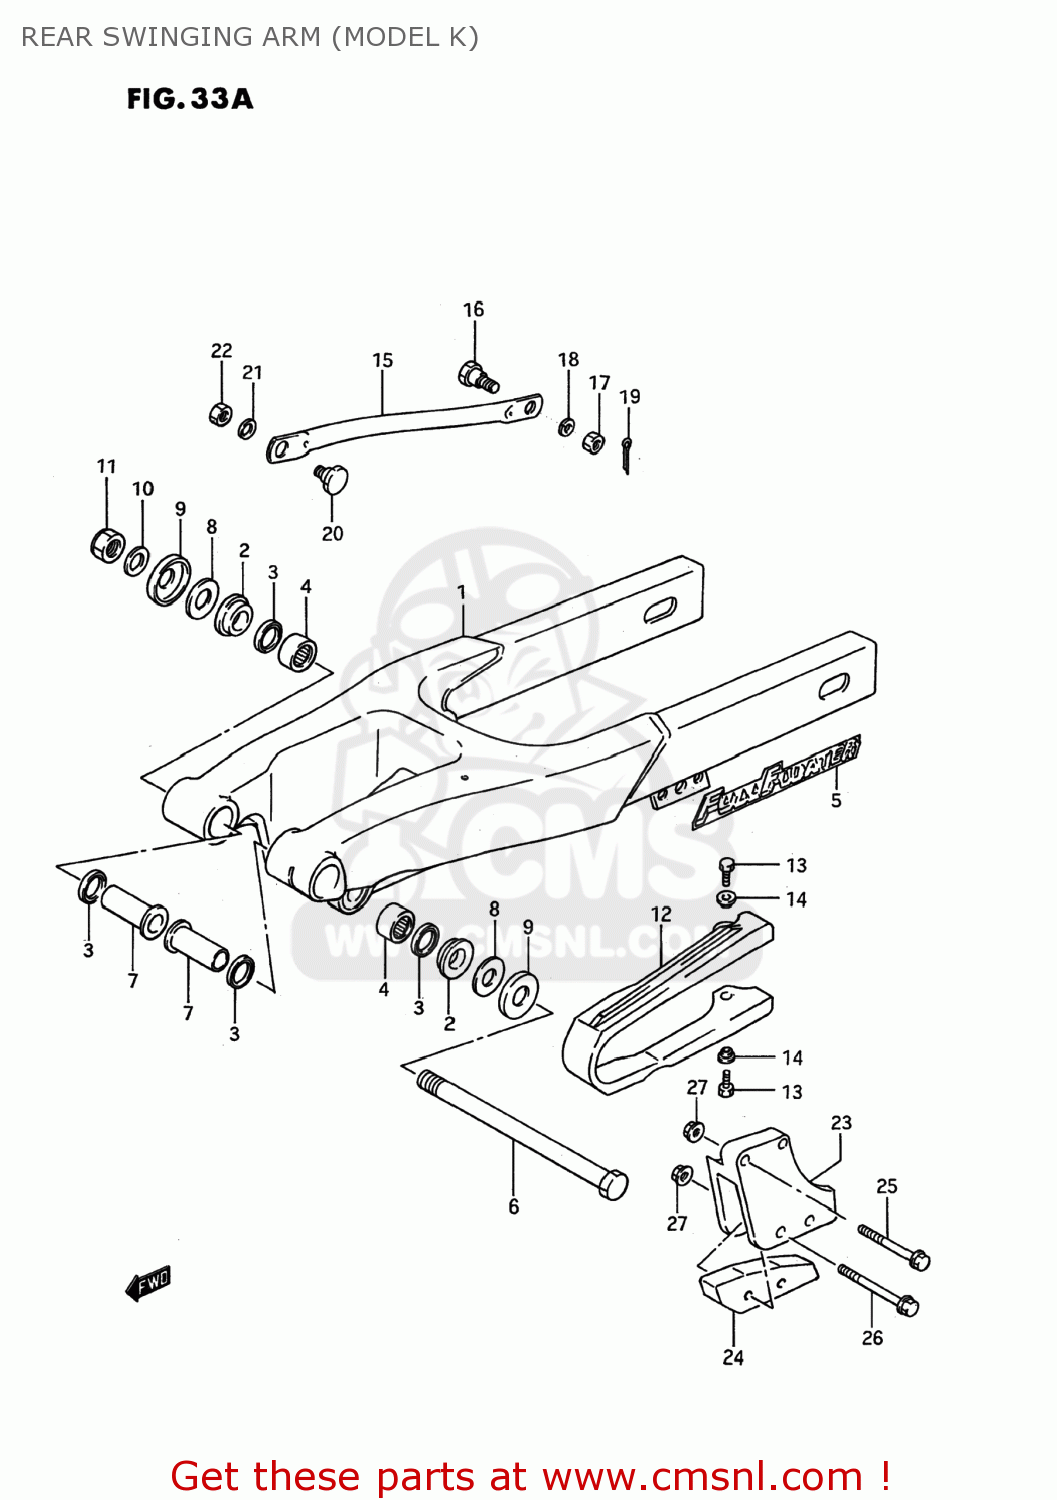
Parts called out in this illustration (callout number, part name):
1	SWING ARM ASSEMBLY,REAR
2	BUSHING,SWGARM PIVOT
3	SEAL,OIL(17X24X3)
4	ROLLER BEARING (17X24X25)
5	EMBLEM,SWING ARM
6	SHAFT,REAR SWING ARM PIVOT
7	SPACER,RR SWGARM PIVOT
8	WASHER
9	COVER,REAR SWING ARM DUST
10	WASHER
11	NUT 12MM
12	BUFFER,CHAIN TOUCH DEFENSE
13	BOLT
14	WASHER
15	TORQUE LINK
16	BOLT(8X21)
17	NUT
18	LOCK WASHER
19	PIN 20X20
20	BOLT(8X21)
21	WASHER
22	NUT
23	GUIDE,CHAIN
24	DEFENSE,CHAIN GUIDE
25	BOLT 6X35
26	BOLT,UNDER
27	NUT
